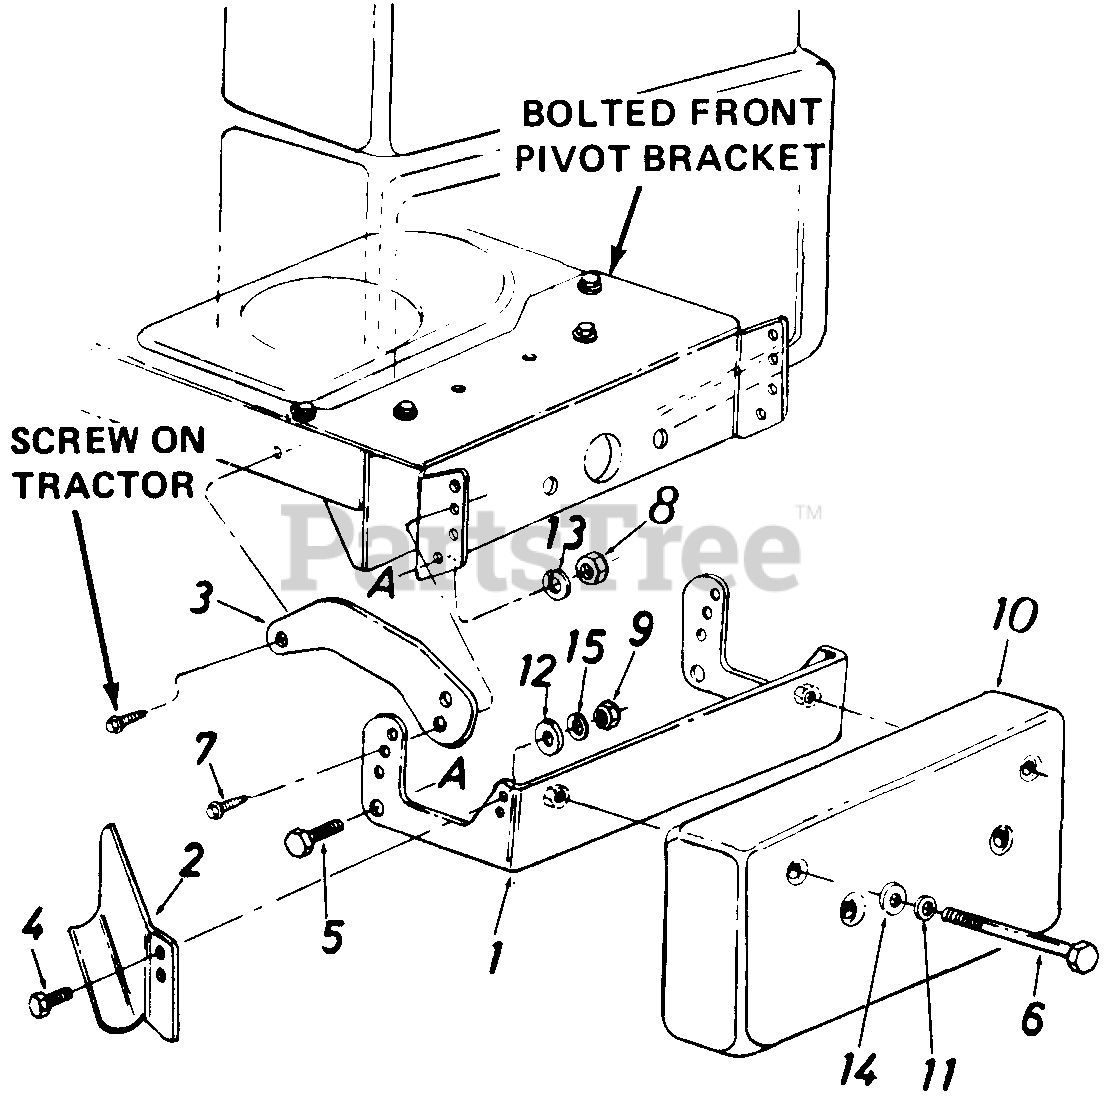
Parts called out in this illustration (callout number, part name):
1	Counterweight Bracket Ass'y.
2	Exhaust Deflector
4	Hex Bolt 1/4-20 x .62" Lg.*
5	Hex Bolt 7/16-20 x 1.0" Lg.
6	Hex Bolt 3/8-16 x 4.5" Lg.
7	Hex AB Tap Scr. 5/16-18 x 1.0" Lg.
8	HexJamNut7/16-20Thd.
9	Hex Nut 1/4-20Thd.*
10	Front Counterweight-38 Lbs.
11	Bell-Wash. .40" I.D. x .88" O.D.
12	Fl-Wash. .28" I.D. x .50" O.D.
13	L-Wash. 7/16" I.D.
14	F l-Wash .39" I.D. x 1.12" O.D.
15	L-Wash. 1/4" I.D.*
